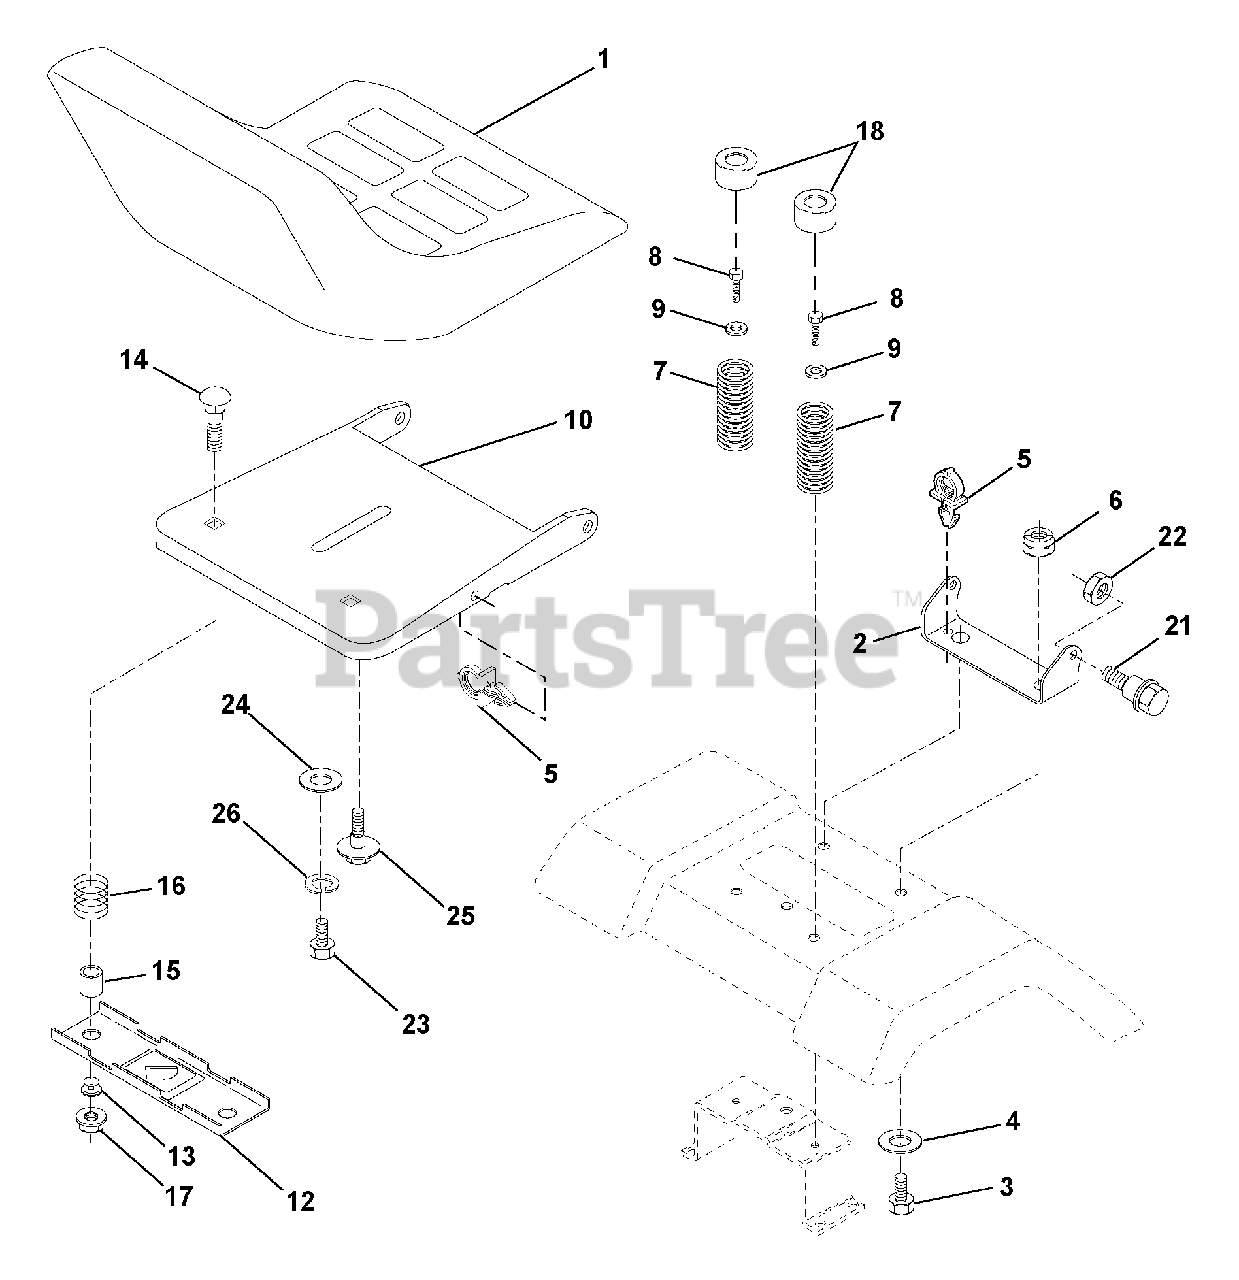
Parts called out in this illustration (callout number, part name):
1	Seat
2	Bracket Pivot Seat 8 720
3	Bolt Fin Hex 3/8-16unc X 1
4	Washer 13/32 X 1 X 10 Ga
5	Clip Push-In
6	Nut Hex w/Ins. 3/8-16 Unc
7	Spring Seat Cprsn 2 250 Blk Zi
8	Screw Thdrol 3/8-16 X 1 Ty-tt
9	Washer 13/32 X 1 X 14 Ga.
10	Pan Seat
12	Bracket Mounting Switch
13	Bushing Snap Blk Nyl 50 Id
14	Bolt Rdhd Sqnk 1/4-20x1-1/2
15	Spacer Split 28x 96 Yel Zinc
16	Spring Cprsn 1 27 Blk Pnt
17	Nut Lock 1/4 Lge Flg Gr 5 Zinc
18	Cap Spring Seat
21	Bolt Shoulder 5/16-18 Unc
22	Nut Hex Lock W/Ins 5/16-18
23	Bolt, Hex Head, Fin 1/2-13 x 7/8 Grade 5
24	Washer 17/32 X 1-3/16 X 12 Ga.
25	Bolt Shoulder 5/16-18 X 62
26	Washer Lock
